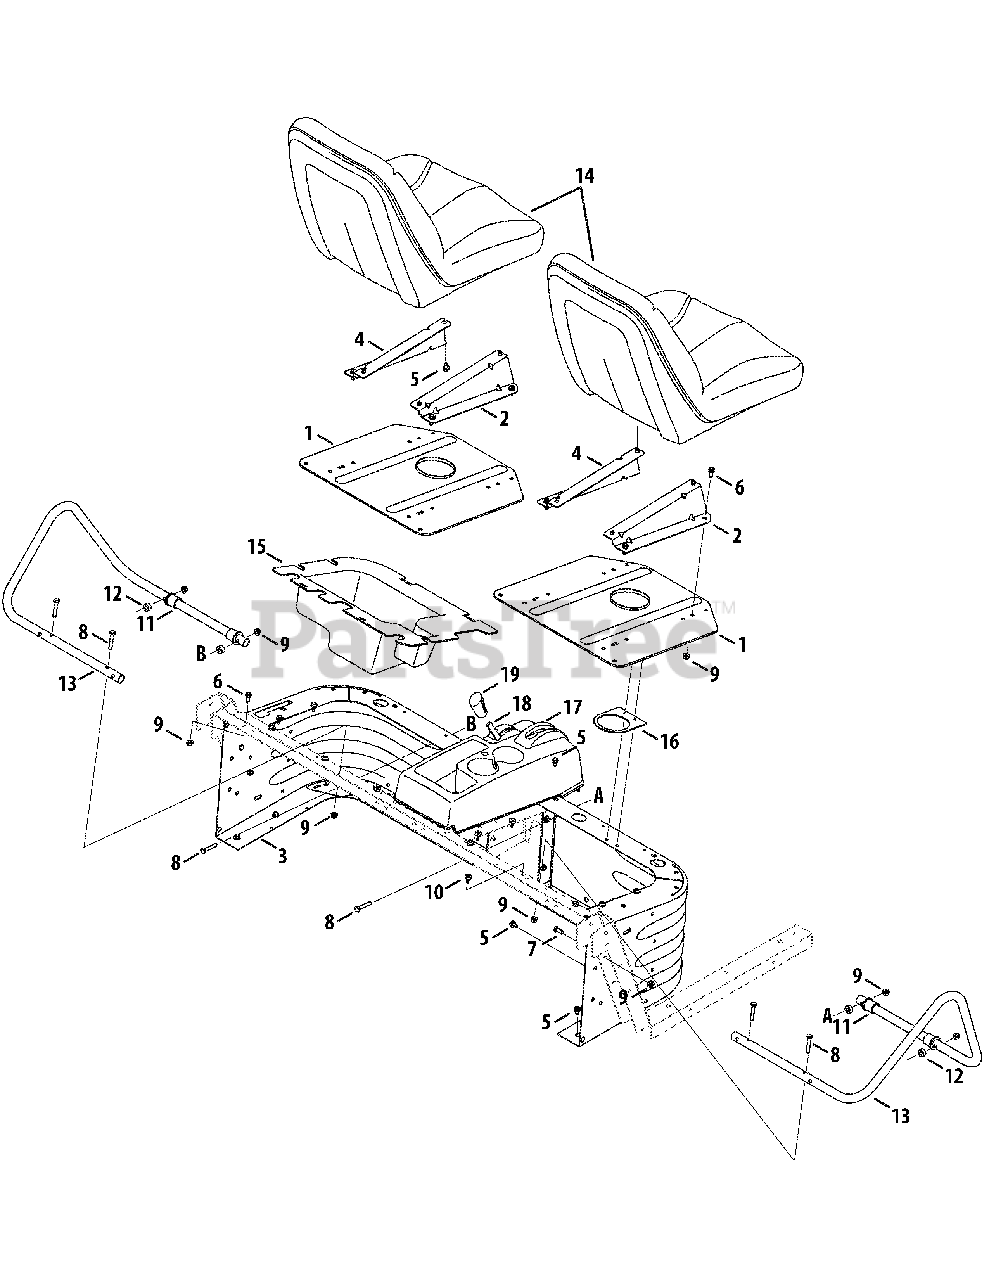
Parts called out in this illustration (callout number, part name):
1	Plate, Seat, Assembly
5	Screw, TT, 5/16-18 x .500
6	Screw, LD, 5/16-18 x .750
7	Screw, 5/16-18 x .75
8	Screw, 5/16-18 x 1.75
9	Nut, Flange Lock, 5/16-18
10	Bumper, .62 Dia. x .3
11	Bearing, Flange, .894 ID x 1.1315
12	Spacer, .315 x .750 x .375 Lg.
14	Seat, High Back
14	Seat, Sport
15	Tray, Seat Box
16	Bracket, Tube, CVT
17	Seat Console
17	Cover, Bench Seat
18	Lever Assembly, Diff Lock
18	Lever Ass’y, Diff Lock, Bench Seat
19	Handle, Select
